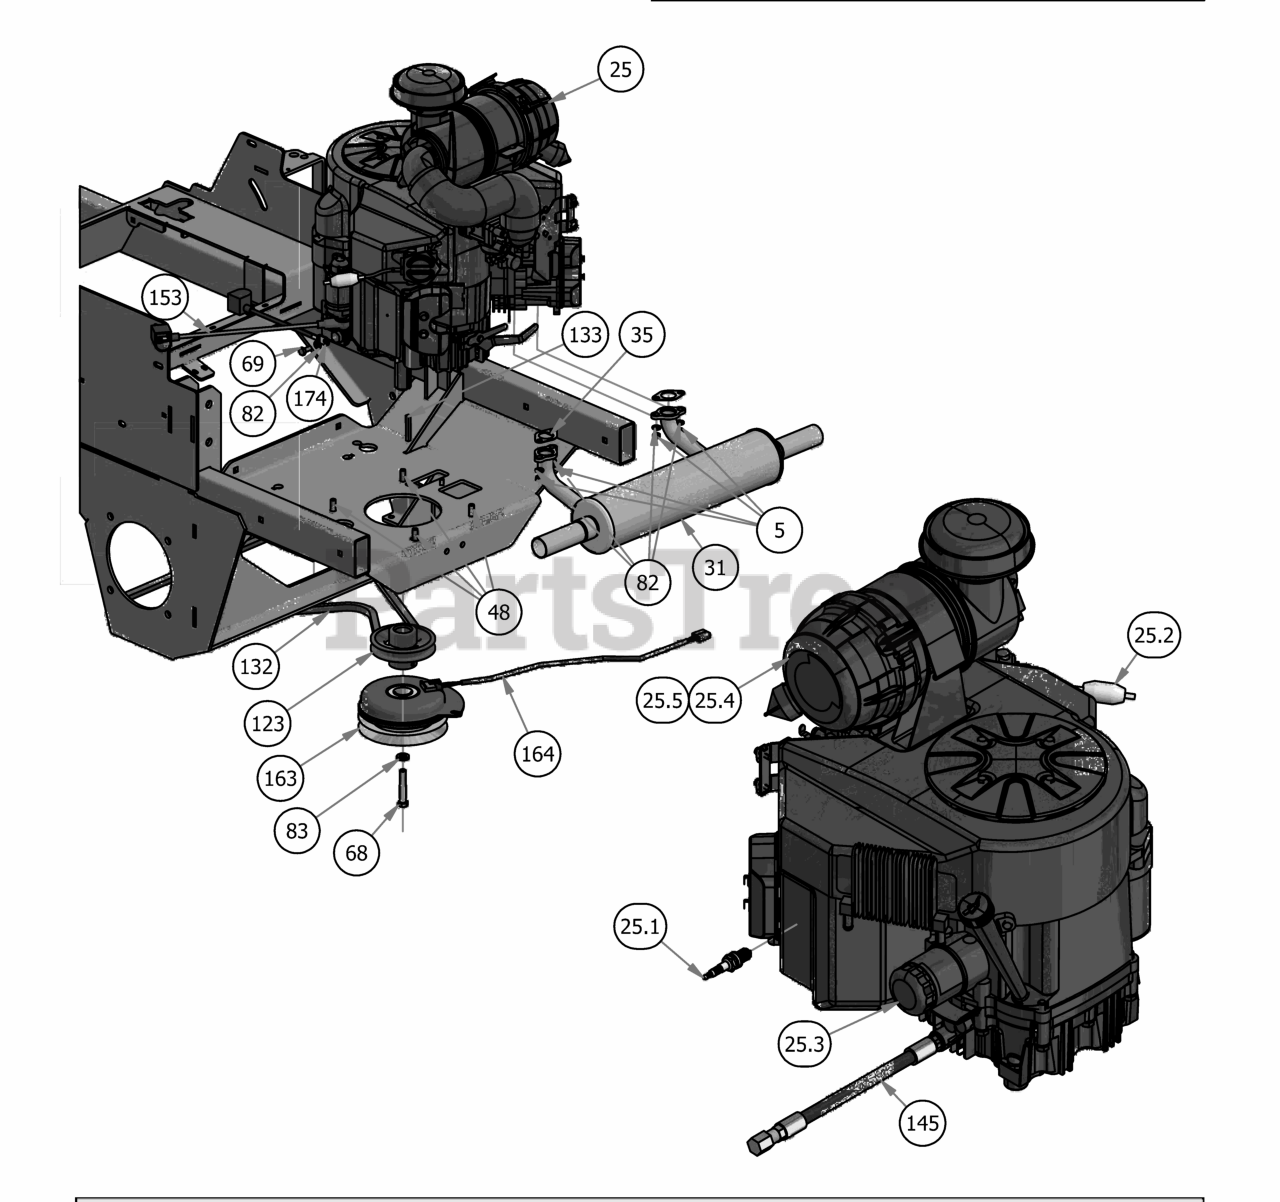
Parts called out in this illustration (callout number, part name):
5	M8-1.25 Zinc Nut
25	Kawasaki FX850 Engine
25.1	Spark Plug - Kawasaki
25.2	Universal Inline Fuel Filter
25.3	Oil Filter
25.4	Canister Air Filter- Outer
25.5	Canister Air Filter- Inner
31	2019 Rebel/Rogue Kawasaki 850 Muffler
35	Exhaust Gasket
48	3/8 x 1 1/8 bolt
68	7/16" x 2 1/2" Hex Bolt
69	M8x1.20x20MM Hex head bolt
82	5/16" Lock Washer
83	7/16" Lock Washer
123	4 3/4 Motor Pulley
132	2019 Rebel Pump Belt
133	1/4 x 2 Square key Stock
145	Kawasaki Oil Drain
153	14" Red Battery Cable-Base Outlaw
163	Clutch Assembly
164	Clutch Pigtail
165	2019 Rigid Frame
174	Starter Cable
